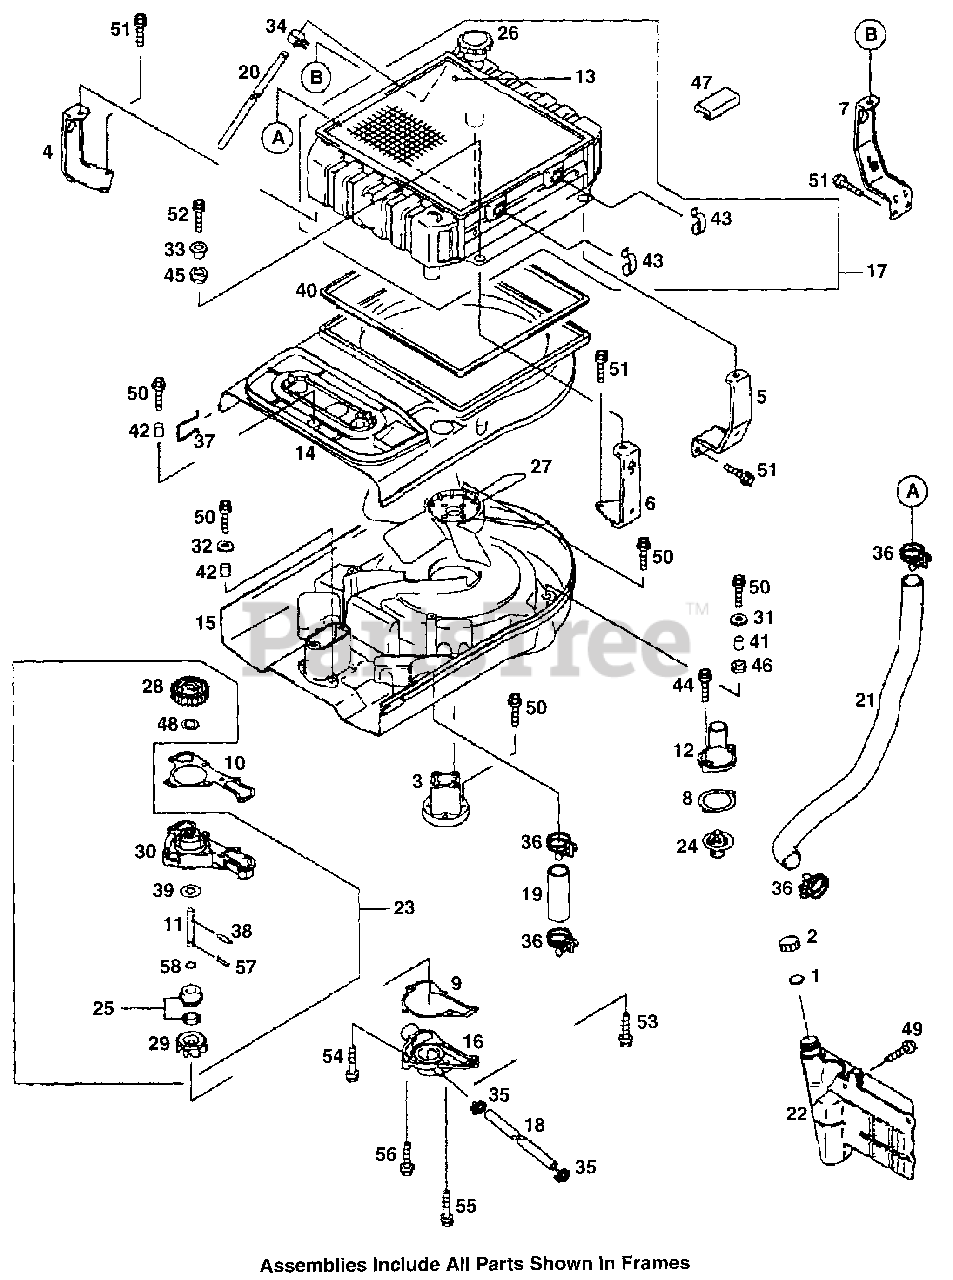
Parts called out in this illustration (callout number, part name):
6	Bracket
7	Bracket
8	Thermostat Cover Gasket
9	Pump Cover Gasket
10	Pump Case Gasket
11	Impeller Shaft
16	Pump Cover
17	Radiator Assembly
18	Cooling Hose, 7.5 x 13.5 x 305
19	Cooling Hose, 24 x 31.2 x 90
20	Cooling Hose, 7.5 x 10.5 x 460
23	Water Pump
24	Thermostat
25	Mechanical Seal
26	Pressure Cap Assembly
31	Washer, 6.5 x 20 x 1.6
49	Flanged Bolt
50	Flanged Bolt
51	Flanged Bolt
52	Flanged Bolt
53	Flanged Bolt
54	Flanged Bolt
55	Flanged Bolt
56	Flanged Bolt
